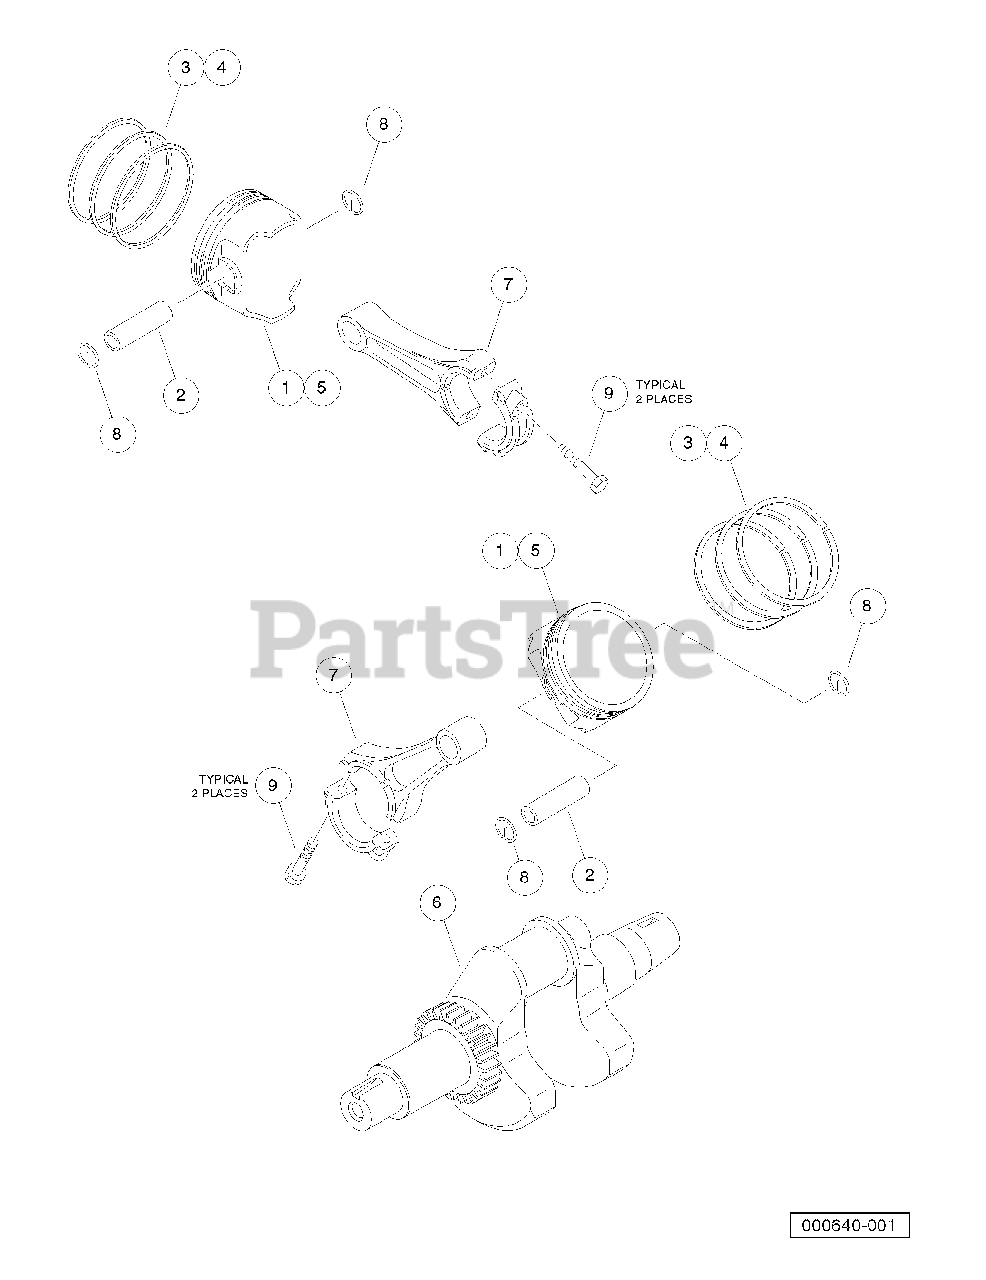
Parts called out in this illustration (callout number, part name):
1	Piston, Engine, Right, Fh
2	Pin, Piston, Engine, Fh
3	Ring, Set, Piston, Fh
4	Ring, Set, Piston L, 0.50, Fh
5	Piston, Engine L, 0.50, Fh
6	Crankshaft, Comp, Fh
7	Kit, Rod, Connecting, Fh
8	Ring, Snap, Pin, Piston, Fh
9	Bolt, Flg, M6 X 1.00 X 35
